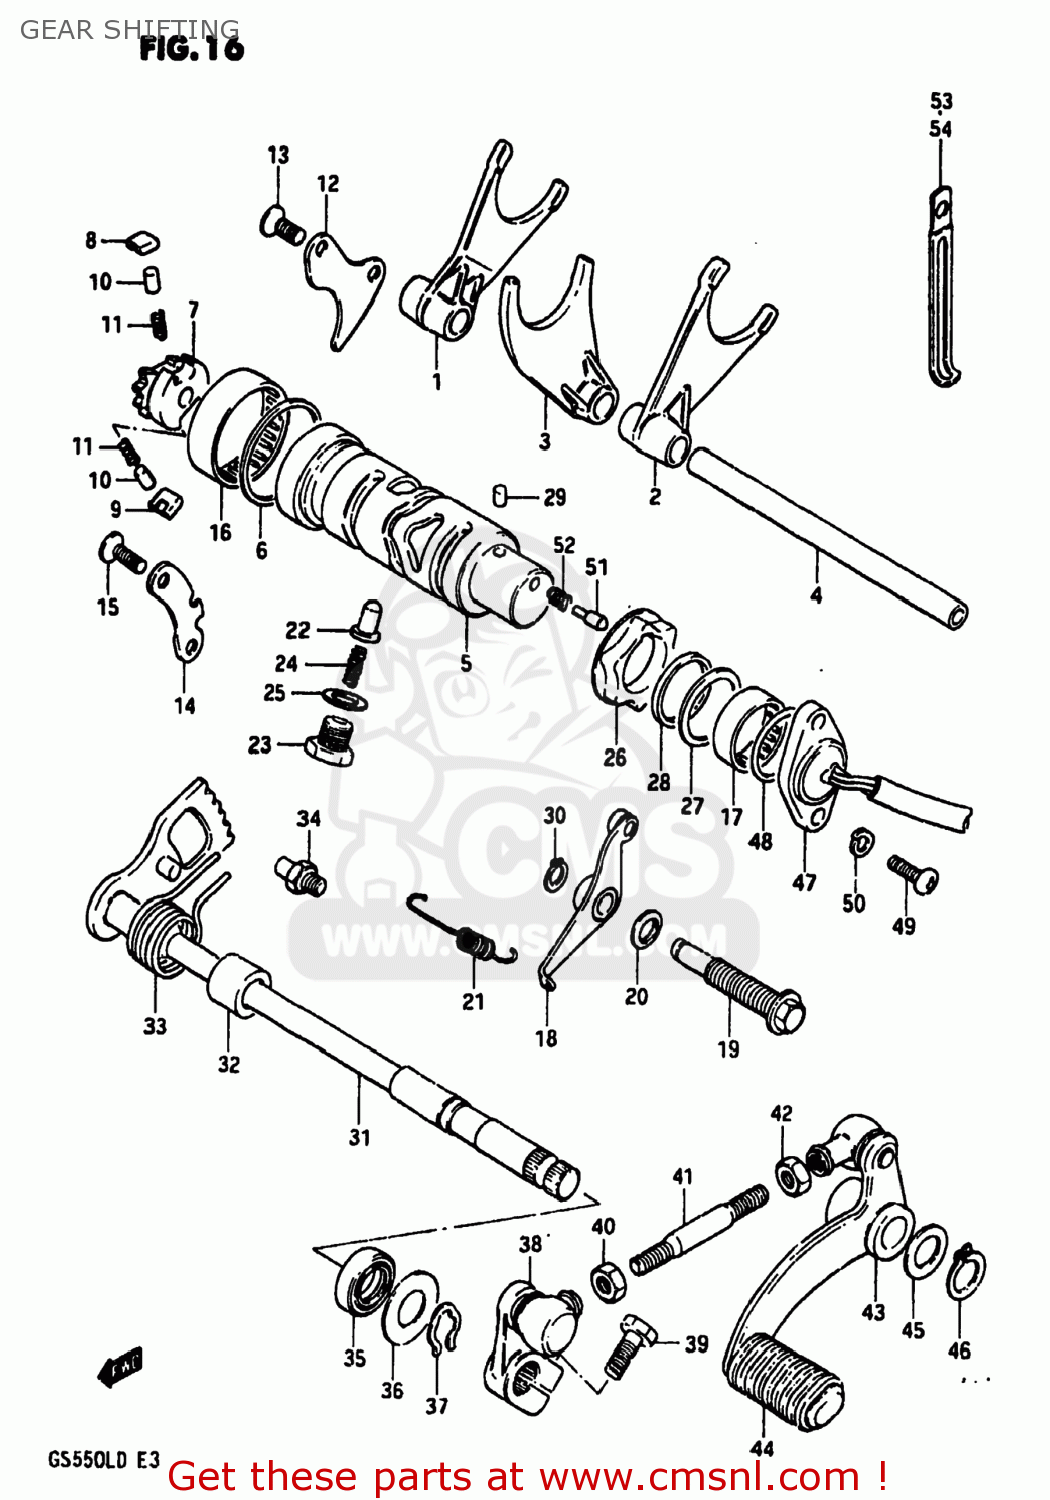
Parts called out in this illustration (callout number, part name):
1	FORK,GEAR SHIFT NO.1
2	FORK,GEAR SHIFT NO.2
3	FORK,GEAR SHIFT NO.3
4	SHAFT,GEAR SHIFT FORK
5	CAM,GEAR SHIFT
6	WASHER (40X49X1)
7	RETAINER,GEAR SHIFT CAM
8	PAWL,GEAR SHIFT NO.1
9	PAWL,GEAR SHIFT NO.2
10	PIN(5X8)
11	SPRING
12	LIFTER,GEAR SHIFT PAWL
13	SCREW
14	GUIDE,GEAR SHIFT CAM
15	SCREW
16	BEARING(43X49X12)
17	BEARING(25X32X12)
18	STOPPER,GEAR SHIFTING
19	HOLDER,SHIFTING CAM STOPPER
20	GASKET(10X14X3.6) (NAS)
21	SPRING
22	STOPPER,GEAR SHIFTING
23	HOLDER,GEAR SHIFT CAM STOP SPR
24	SPRING
25	GASKET(14X19.2X2) (NAS)
26	PLATE,GEAR SHIFT CAM STOPPER
27	WASHER
28	WASHER
29	PIN 4X6
30	CIRCLIP
31	SHAFT,GEAR SHIFT
32	SPACER(12X20X15.3)
33	SPRING
34	STOPPER,GEAR SHIFT CAM
35	OIL SEAL
36	WASHER (12.5X27X1.6)
37	SPRING,RETAINER
38	ARM,GEAR SHIFT LINK
39	BOLT
40	NUT
41	ROD,GEAR SHIFT LINK
42	NUT
43	LEVER ASSEMBLY,GEAR SHIFTING
44	RUBBER,PEDAL
45	WASHER(12.5X20X1)
46	CIRCLIP
47	SWITCH ASSEMBLY,GEAR SHIFT
48	O-RING (D:2.4 ID:26.2)
49	SCREW
50	LOCK WASHER
51	PIN(5X15.5)
52	SPRING
53	CLAMP
54	CLAMP
